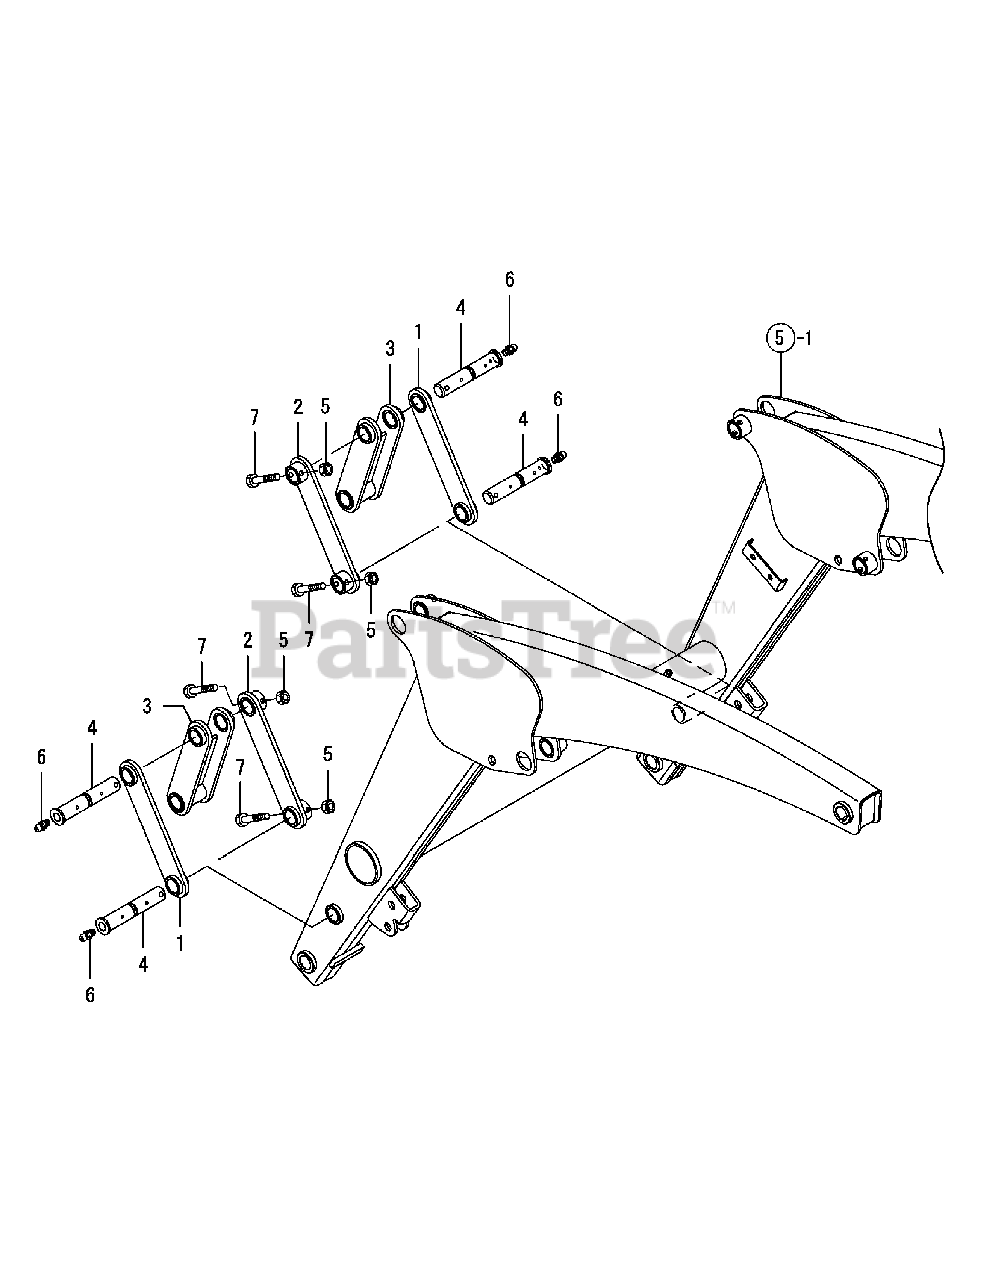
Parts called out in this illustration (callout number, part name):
1	LINK PLATE L CMP
2	LINK PLATE R CMP
3	LINK, FRONT CMP
4	9/8 STEPPED PIN
7	BOLT, 8 X 60 PLATED
